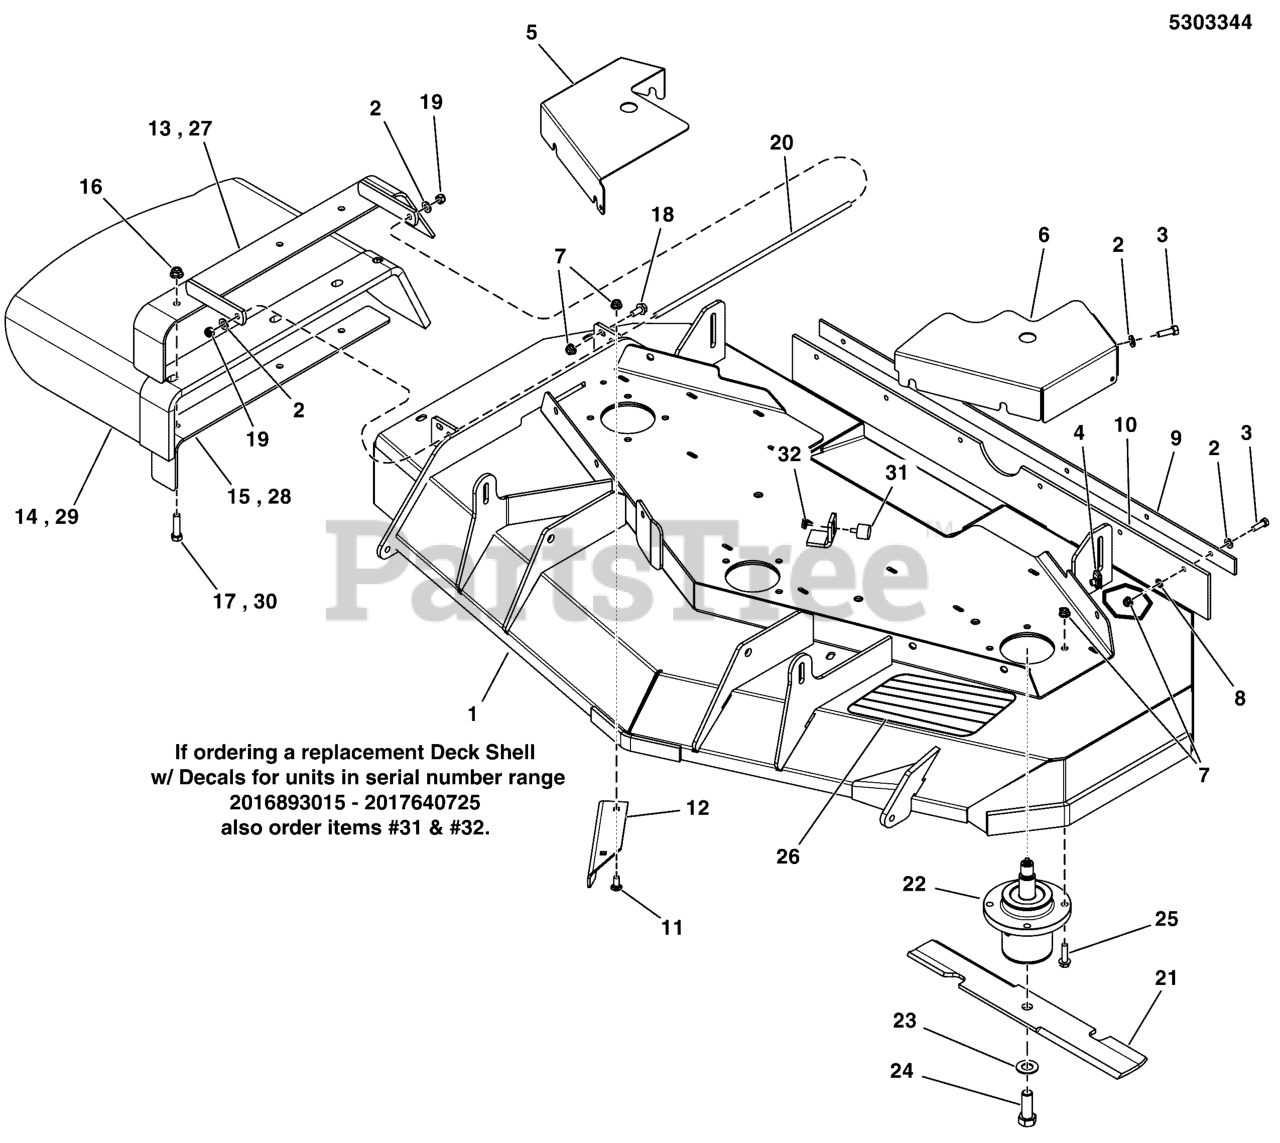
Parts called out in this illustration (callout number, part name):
1	DECK SHELL W/ DECALS, 52, S125XT (SV)
1	DECK SHELL W/ DECALS, S125XT-52, DOM
2	WASHER, 5/16" SAE
3	BOLT, 5/16-18 X 1 GD5 YZ
4	BODY CLIP, 5/16-18-7GA MATERIAL
5	GUARD, RH 52", 560/700/125
6	GUARD, 52 DECK, LH - RED
7	NUT, 5/16-18 HEX NYLOCK FLANGE
8	5/16 PUSH-ON NUT RETAINER, STL, CZ
9	PLATE, SUPPORT - BLK
10	FLAP, STRIPER, 52 DECK
11	BOLT, 5/16-18 X 3/4, CARRIAGE
12	PLATE, DEFLECTOR, 52 DECK - BLK
13	WELD, FRAME CHUTE, 52 - BLK
14	CHUTE, Discharge
15	SUPPORT, DISCHARGE CHUTE, 52 - BLK
16	NUT, 3/8-16 HEX NYLOCK FLANGE
17	BOLT, 3/8-16 X 1-1/2" GD5 CZ
18	BOLT, 5/16-18 X 3/4 GD5
19	NUT, 5/16-24 HEX NYLON LOCK
20	ROD, MOUNT, CHUTE 61, CZ
21	BLADE, 18 X .25 X 2.5, 1 X 3.5 (SET OF 3)
22	ASSM, SPINDLE, LOW PROFILE
23	WASHER, 5/8 GRADE 8, YZ
24	BOLT, 5/8-11 X 1-3/4 GD8
25	BOLT, 5/16-18 X 1 1/4 FLANGE
26	SAFETY WALK, 4.00 X 7.50
27	WELD, MOUNT, DISCHARGE CHUTE - BLK
28	SUPPORT, DISCHARGE CHUTE - BLK
29	CHUTE, RUBBER DISCHARGE (5104442)
30	BOLT, 3/8-16 X 1-1/2, CARRIAGE, GD5, CZ
31	BUMPER, RUBBER 1/4-20
32	NUT, 1/4-20 HEX SERR. FLANGE
